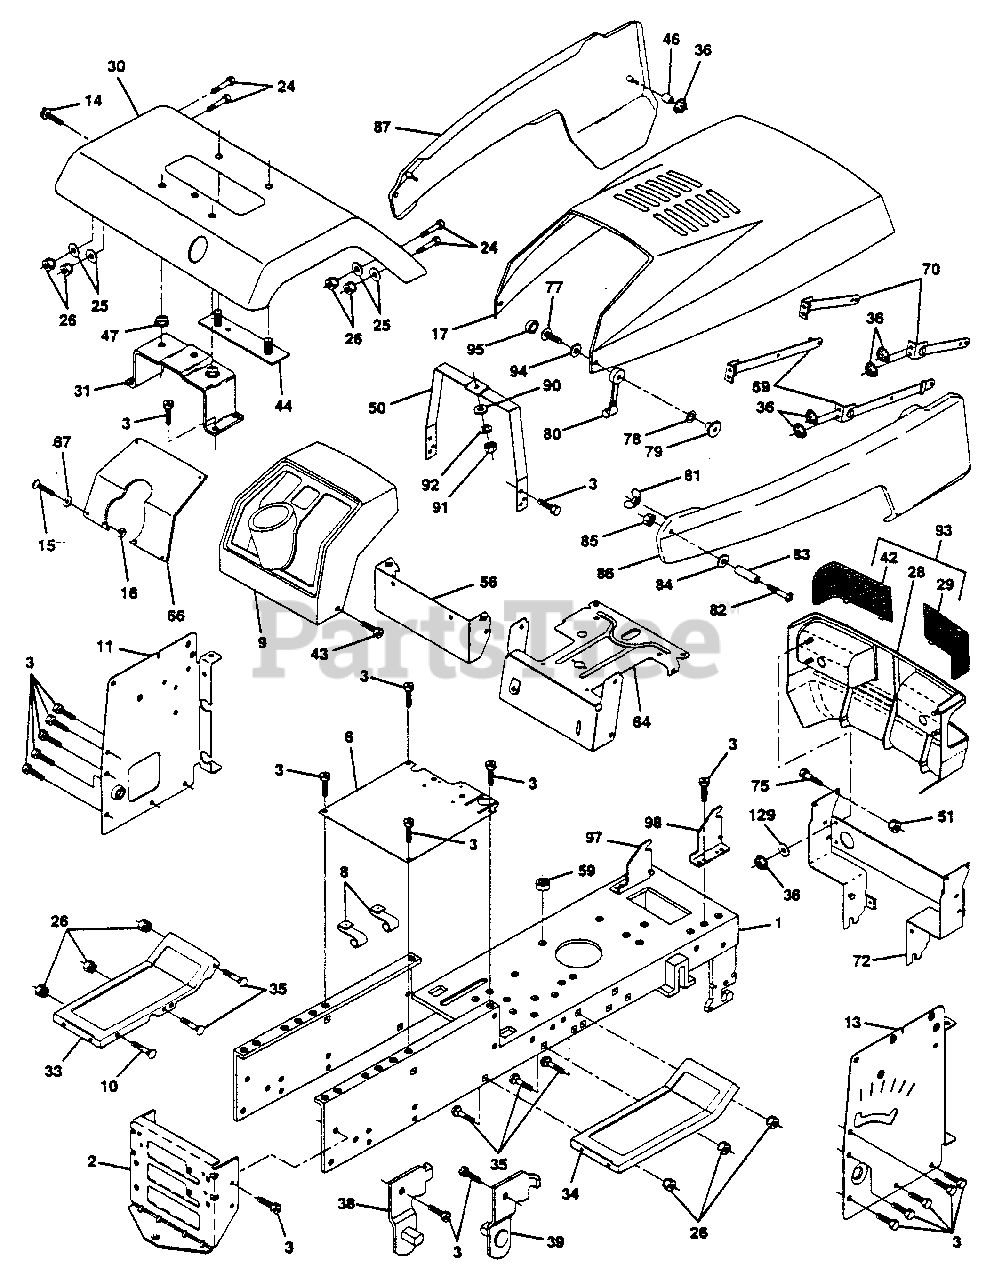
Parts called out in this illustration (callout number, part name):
2	Drawbar
3	Screw, Thdrol 3/8-16 x 3/4
8	Clip, Insulator
10	Bolt, Carriage 318-16 UNC x 1
11	Dash Panel, LH
13	Dash Panel, RH
14	Screw, Thd., Roll. 3/8-16 x 1 /2
15	Screw, Machine 5/16-18 UNC x 3/4
16	Nut, Hex, Keps 5/16-18 UNC
20	Plate, Battery Support
24	Bolt Fin Hex 3/8-16 UNC x 1 Gr. 5
25	Washer 13/32 x 13/16 x 12 Gauge
26	Nut Lock Hex W/Ins. 3/8-16 UNC
28	Grille
29	Lens, Headlight, RH, Smoked
30	Fender
31	Bracket Fender
33	Footrest, LH
34	Footrest, RH
35	Bolt, Carriage 3/8-16 x 3/4
38	Pivot Bracket Assembly, Rear, LH
39	Pivot Bracket Assembly, Rear, RH
42	Lens, Headlight, LH, Smoked
43	Screw, Thd., Roll. 3/8-16 x 3/4
44	Strap, Fender
47	Nut, Push, Nylon
50	Support, Dash
51	Nut Lock W/Insert 1/4-20 UNC
56	Extension Dash
59	Bushing, Snap Split
64	Dash, Lower
66	Plate, Dash
67	Washer 11/32 x 11/16 x 16 Gauge
69	Strap Assembly, Hinge, Rear
70	Strap Assembly, Hinge, Front
72	Support Assembly, Grille
75	Bolt, Shoulder 1/4-20 UNC
77	Screw, Machine, Cross Pan Head #10-24 x 1/2
78	Washer, Lock #10
79	Nut, Weld
80	Latch, Chute
81	Wing Nut, Plastic 1/4-20
82	Screw, Machine, Cross Pan Head #10-24 x 1-1/4
83	Spacer, Split #10 x 3/4
84	Washer 7/32 x 1/2 x 18 Gauge
85	Nut, Hex, Keps #10-24 UNC
86	Side Panel, RH
87	Side Panel, LH
90	Washer 9/32 x 3/4 x 16 Gauge
91	Bolt, Hex, Fin. 3/8-16 UNC x 3/4
92	Washer, Lock, Hvy-Hlcl 1/4
93	Grill Assembly
94	Washer, Cap
95	Cap, Black
97	Pivot Bracket Assembly, LH
98	Pivot Bracket Assembly, RH
129	Washer 9/32 x 5/8 x 16 Ga.
